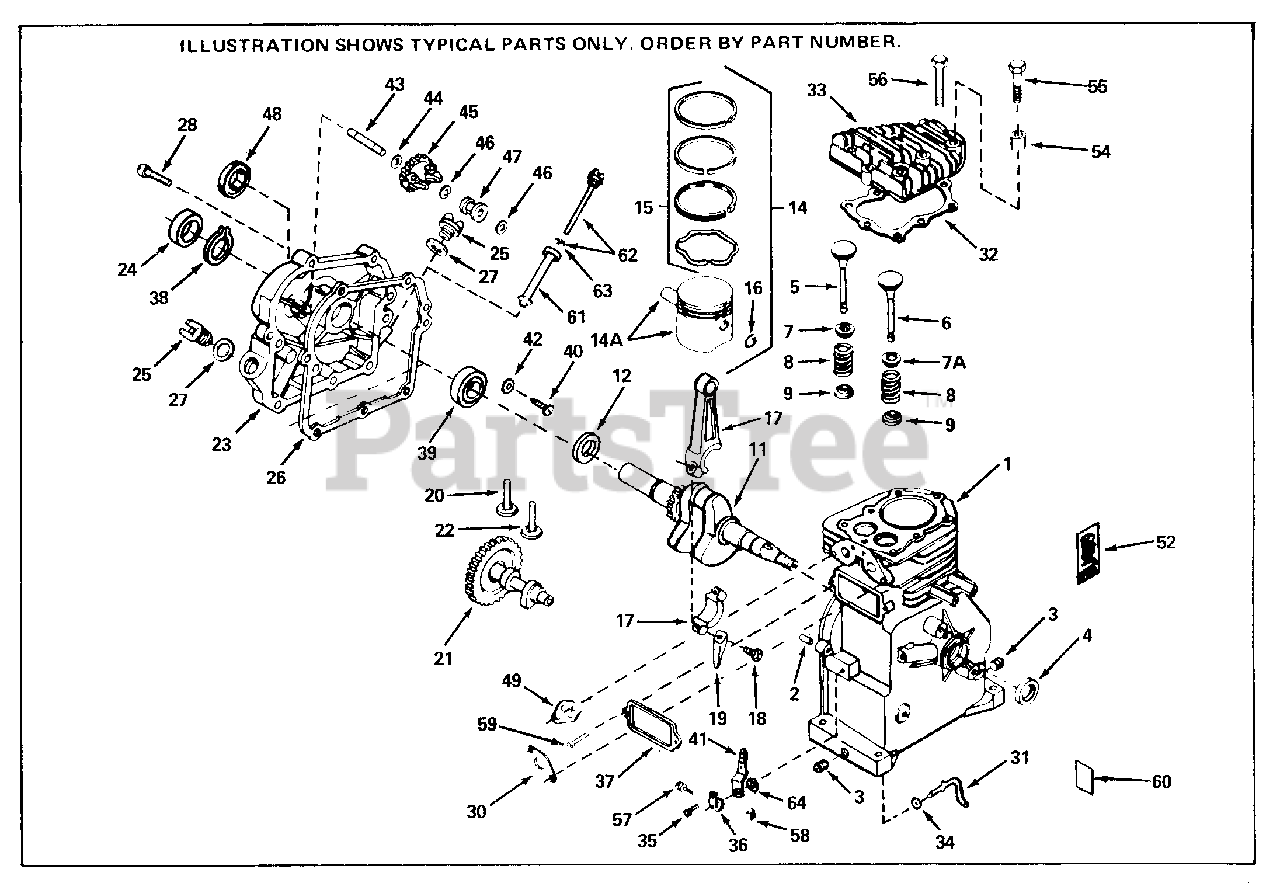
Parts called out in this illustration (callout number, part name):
1	"Cylinder (Incl. 2, 3 & 4) 2-5/8" Bor e
2	Dowel Pin
3	Oil Drain Plug (Sq. hd., 1/4-18)
4	Seal, Oil
5	Intake Valve (Std.) (Incl. 9)
5	Intake Valve (1/32" OS) (Incl. 9)
6	Exhaust Valve (Std.) (Incl. 151)
6	Exhaust Valve (1/32" OS) (Incl. 151)
7	Valve Spring Cap (Intake)
7A	Cap, Upper valve spring (Exhaust)
8	Spring, Valve
9	Cap, Lower valve spring
11	Crankshaft
12	Washer, Thrust (Use as required)
14	Piston, Pin & Ring Set (Std.) (2-5/8" Bore) These piston, pin and ring se ts and pistons have been superceded i nto a new piston, pin and ring set as sembly. As of this update the ring se ts (34854, 34855, 34856) are still av ailable.It will be nece
14	Piston, Pin & Ring Set (.010" OS) The se piston, pin and ring sets and pist ons have been superceded into a new p iston, pin and ring set assembly. As of this update the ring sets (34854, 34855, 34856) are still available.It will be necessary to note
14	Piston, Pin & Ring Set (.020" OS) The se piston, pin and ring sets and pist ons have been superceded into a new p iston, pin and ring set assembly. As of this update the ring sets (34854, 34855, 34856) are still available.It will be necessary to note
14A	Piston & Pin Ass'y. (Std.)(Incl. 16) (2-5/8") These piston, pin and ring sets and pistons have been superceded into a new piston, pin and ring set assembly. As of this update the ring sets (34854, 34855, 34856) are still available.It will be necessa
14A	Piston & Pin Ass'y. (.010" OS) (Incl. 16) These piston, pin and ring se ts and pistons have been superceded i nto a new piston, pin and ring set as sembly. As of this update the ring se ts (34854, 34855, 34856) are still av ailable.It will be nece
14A	Piston & Pin Ass'y. (.020" OS) (Incl. 16) These piston, pin and ring se ts and pistons have been superceded i nto a new piston, pin and ring set as sembly. As of this update the ring se ts (34854, 34855, 34856) are still av ailable.It will be nece
15	Ring Set (Std.) (2-5/8" Bore) These p iston, pin and ring sets and pistons have been superceded into a new pisto n, pin and ring set assembly. As of t his update the ring sets (34854, 3485 5, 34856) are still available.It will be necessary to note on
15	Ring Set (.010" OS) These piston, pin and ring sets and pistons have been superceded into a new piston, pin and ring set assembly. As of this update the ring sets (34854, 34855, 34856) are still available.It will be necess ary to note on the engine t
15	Ring Set (.020" OS) These piston, pin and ring sets and pistons have been superceded into a new piston, pin and ring set assembly. As of this update the ring sets (34854, 34855, 34856) are still available.It will be necess ary to note on the engine t
16	Piston Pin Retaining Ring
17	Rod Assy., Connecting (Incl. 18 & 19)
18	Bolt, Connecting rod
19	Dipper, Oil
20	Valve Lifter
21	Camshaft
22	Valve Lifter
23	Cover, Cylinder Incl. 24, 25, 27 & 4 3
24	Oil Seal As req.)
24	Oil Seal equired)
26	Cylinder Cover Gasket
28	Screw, 1/4-20 x 1" (Use as required)
28	Screw, 1/4-20 x 1-1/4" Use as requir ed
30	Intake Pipe Gasket
31	Rod, Governor
32	Gasket, Cylinder head
33	Cylinder Head Incl. with some short b locks
34	Flat Washer
35	Screw, 8-32 x 5/16"
36	Clamp, Governor lever
37	Gasket, Breather
41	Lever, Governor
43	Shaft, Mechanical governor
44	Washer, Flat
45	Gear Assy., Governor (Incl. 44)
46	Retaining Ring
47	Spool, Governor
49	Gasket, Intake pipe
52	Decal, Name
60	Decal, Instruction
61	Tube, Oil fill
62	Dipstick (Incl. 63)
63	"O" Ring
